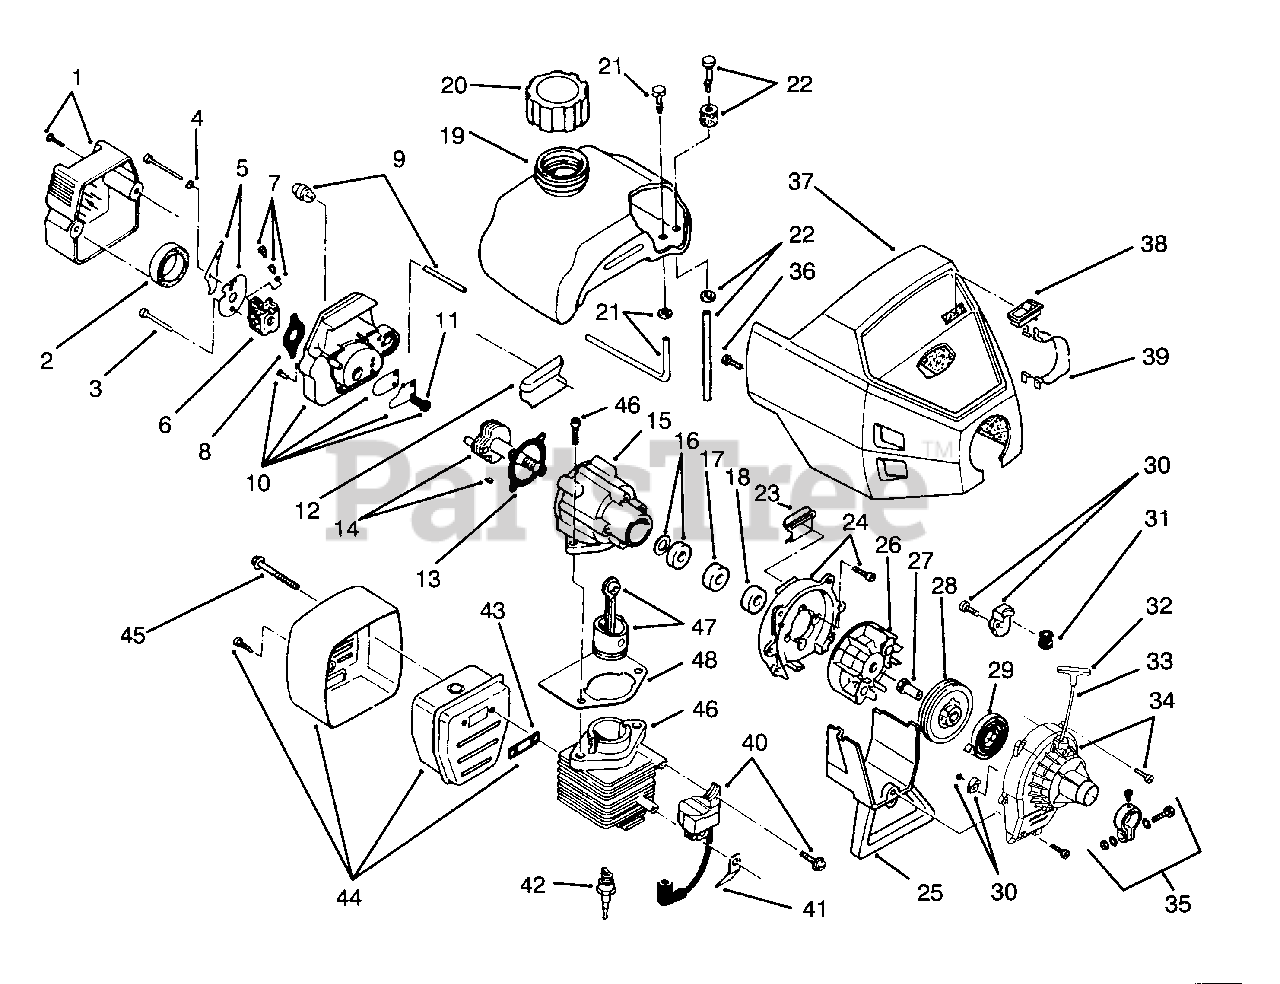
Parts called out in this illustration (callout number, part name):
1	Assy.-Carburetor/Air Clean. (Inc. Ref. No. 2)
2	Filter-Air Cleaner
3	Screw-Carburetor
4	Washer-Wave
5	Choke-Lever and Plate
6	Assembly-Carburetor
7	Throttle Adj.-Walbro
8	Gasket-Carb. (10 Pack)
9	Assy.-Primer and Hose
10	Assembly-Carb. Mount (Incl. Ref. No. 11 & 13)
11	Assembly-Reed
12	Pad-Mounting, Rear
13	Gasket (10 Pack)
14	Assembly-Power Shaft
15	Assy.-Crankcase (Incl. Ref. No. 14-18)
16	Assembly-Inner Bearing
18	Assembly-Outer Bearing
19	Assemby-Fuel Tank (Incl. Ref. No. 20-22)
20	Assembly-Fuel Cap
21	Assembly-Return Line
22	Assembly-Fuel Line
23	Pad-Mounting, Front
24	Assembly-Shroud
25	Shroud Extension & Stand
26	Assembly-Flywheel
27	Square Nut Drive
28	Assembly-Recoil Pulley
29	Spring-Recoil
30	Assembly-Pulley Retainer
31	Guide-Rope
32	Handle-Pull
34	Assembly-Starter Housing
35	Assembly-Upper Clamp
36	Screws-Engine Cover
37	Assembly-Engine Cover
39	Lead Wires
40	Assembly-Module
41	Tab-Ground
42	Spark Plug
43	Gasket-Exhaust (10 Pack)
44	Assembly-Muffler
45	Bolt-Muffler
46	Assembly-Cylinder (Incl. Ref. No. 48)
47	Assembly-Piston & Rod
48	Gasket-Cylinder
